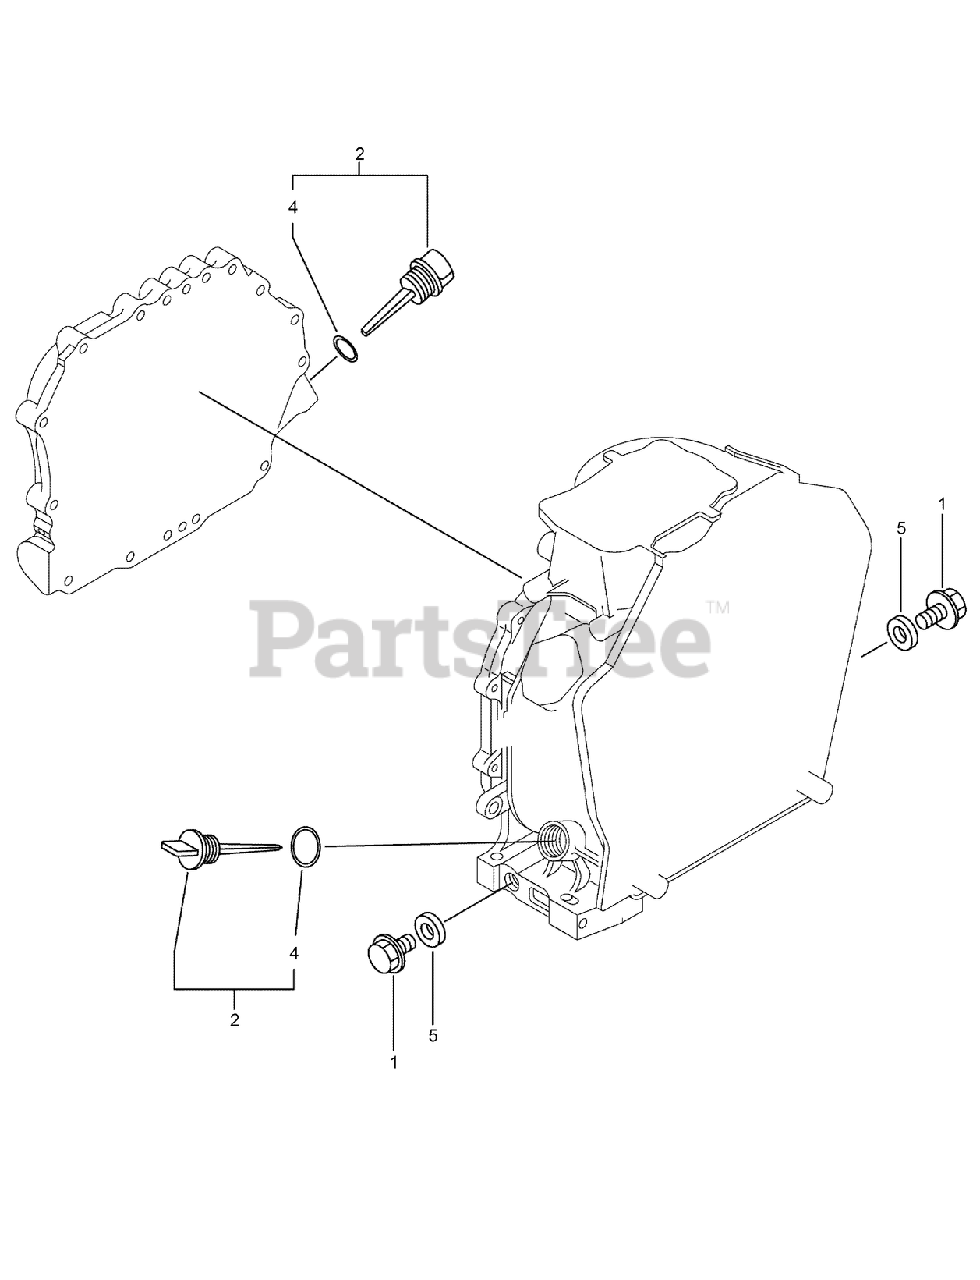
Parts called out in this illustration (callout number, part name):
1	PLUG-DRAIN
2	CAP ASM
4	O-RING
5	WASHER-SEAL
